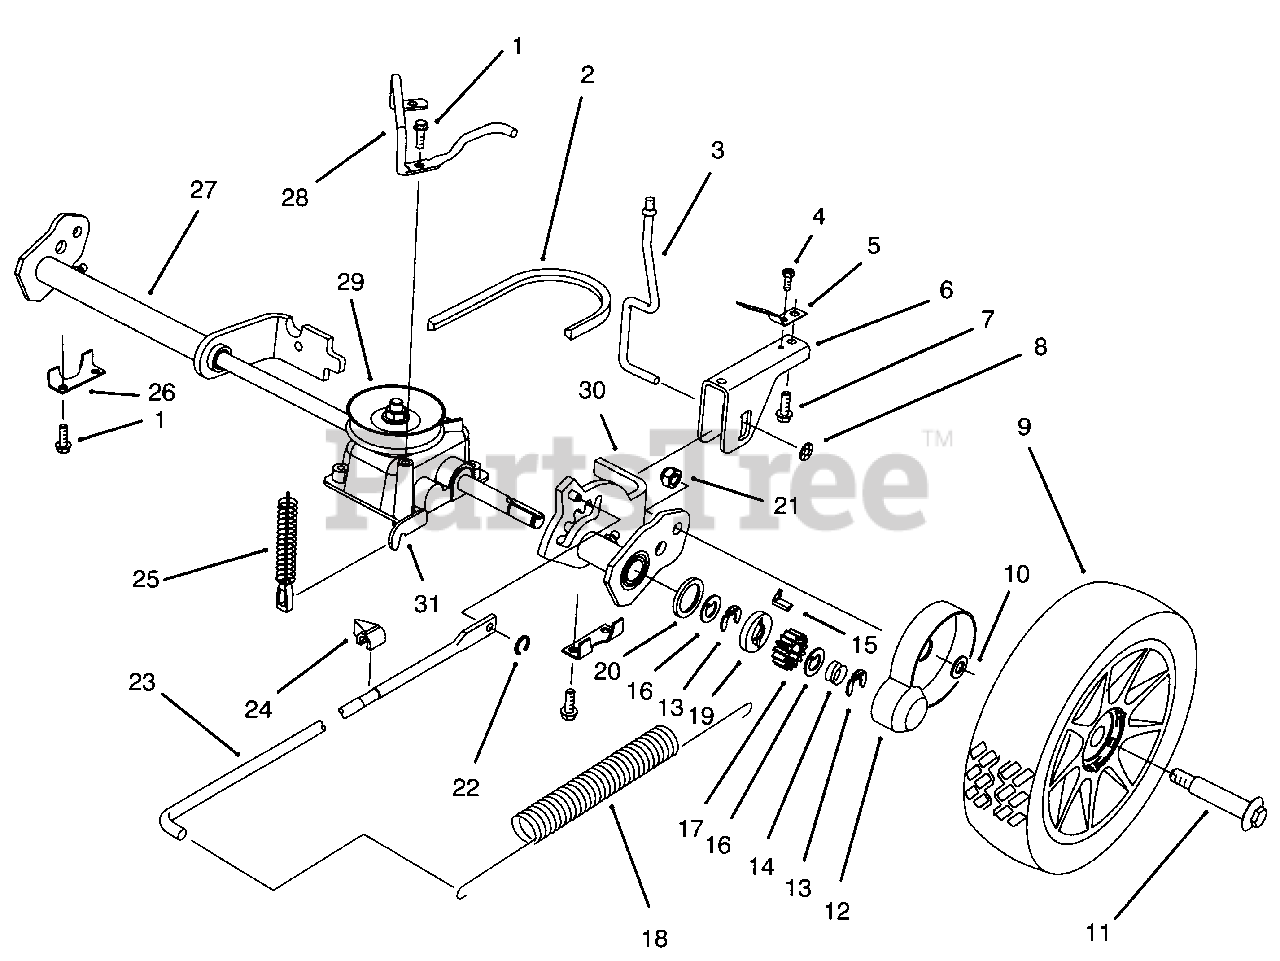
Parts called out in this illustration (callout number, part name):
1	Screw-Tapping
2	V-Belt-Gear Case
3	Rod-Trigger
4	Screw-Tapping
5	Spring-Trigger Retainer
6	Saddle-H.O.C.
9	Wheel & Tire Assembly
10	Spacer-Wheel
11	Bolt-Shoulder
12	Cover-Wheel
13	Ring-Retaining
14	Spring-Compression
15	Key-Rocking L.H.
16	Washer-Thrust Keyed
17	Gear-Pinion
18	Spring-Counterbalance
20	Ring-Friction
21	Nut-Lock
22	Ring-Grip
23	Rod-Link
24	Indicator-H.O.C.
25	Spring-Compression
26	Plate-Securing Rear
27	Arm-R.H. Pivot
28	Retainer-Belt
29	Case-Gear
30	Arm-L.H. Pivot
31	Bracket-Traction
